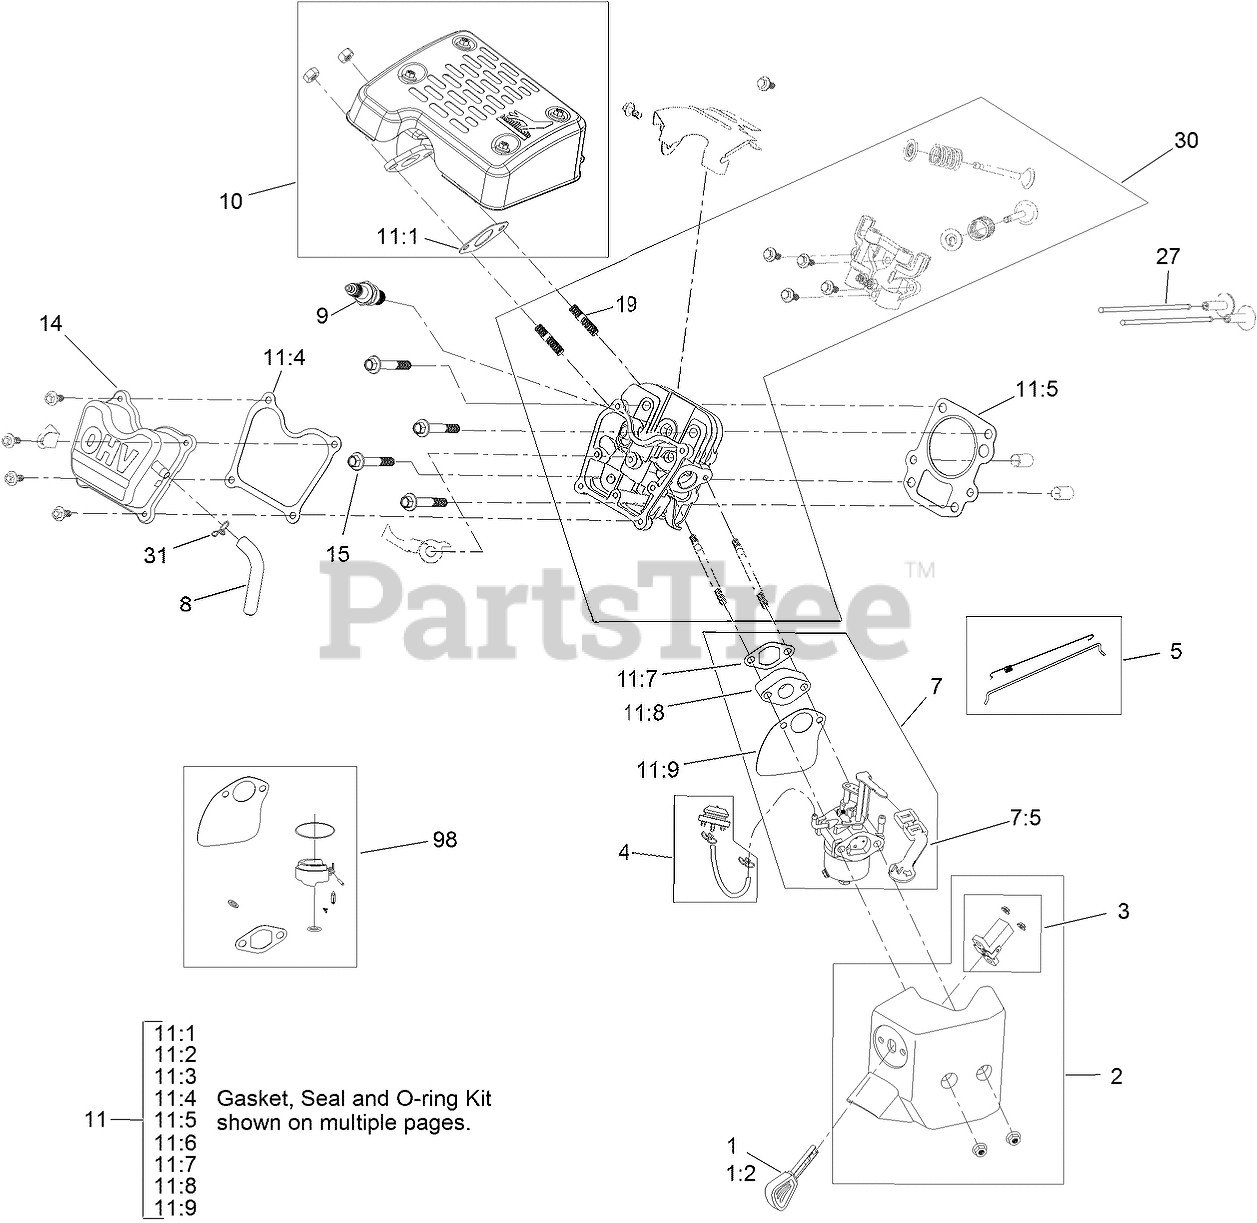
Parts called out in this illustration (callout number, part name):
1	KEY AND LANYARD KIT
2	HEATER BOX KIT
3	SWITCH KIT
4	PRIMER BULB KIT
5	GOVERNOR KIT
7	COMPLETE CARB SERVICE KIT
7:5	LEVER-CHOKE
8	TUBE-BREATHER
9	SPARK PLUG
10	MUFFLER KIT
11	GASKET, SEAL AND O-RING KIT
11:1	GASKET-EXHAUST
11:2	SEAL-OIL
11:3	SEAL-OIL
11:4	GASKET-COVER, VALVE
11:5	GASKET-HEAD, CYLINDER
11:6	GASKET-COVER, CRANKCASE
11:7	GASKET-INSULATOR
11:8	INSULATOR-CARBURETOR
11:9	GASKET-CARBURETOR
14	VALVE COVER ASM
15	SCREW-HHF
19	STUD-EXHAUST
27	ROD-PUSH
30	COMPLETE HEAD ASM
31	CLAMP-HOSE
98	CARBURETOR REPAIR KIT
